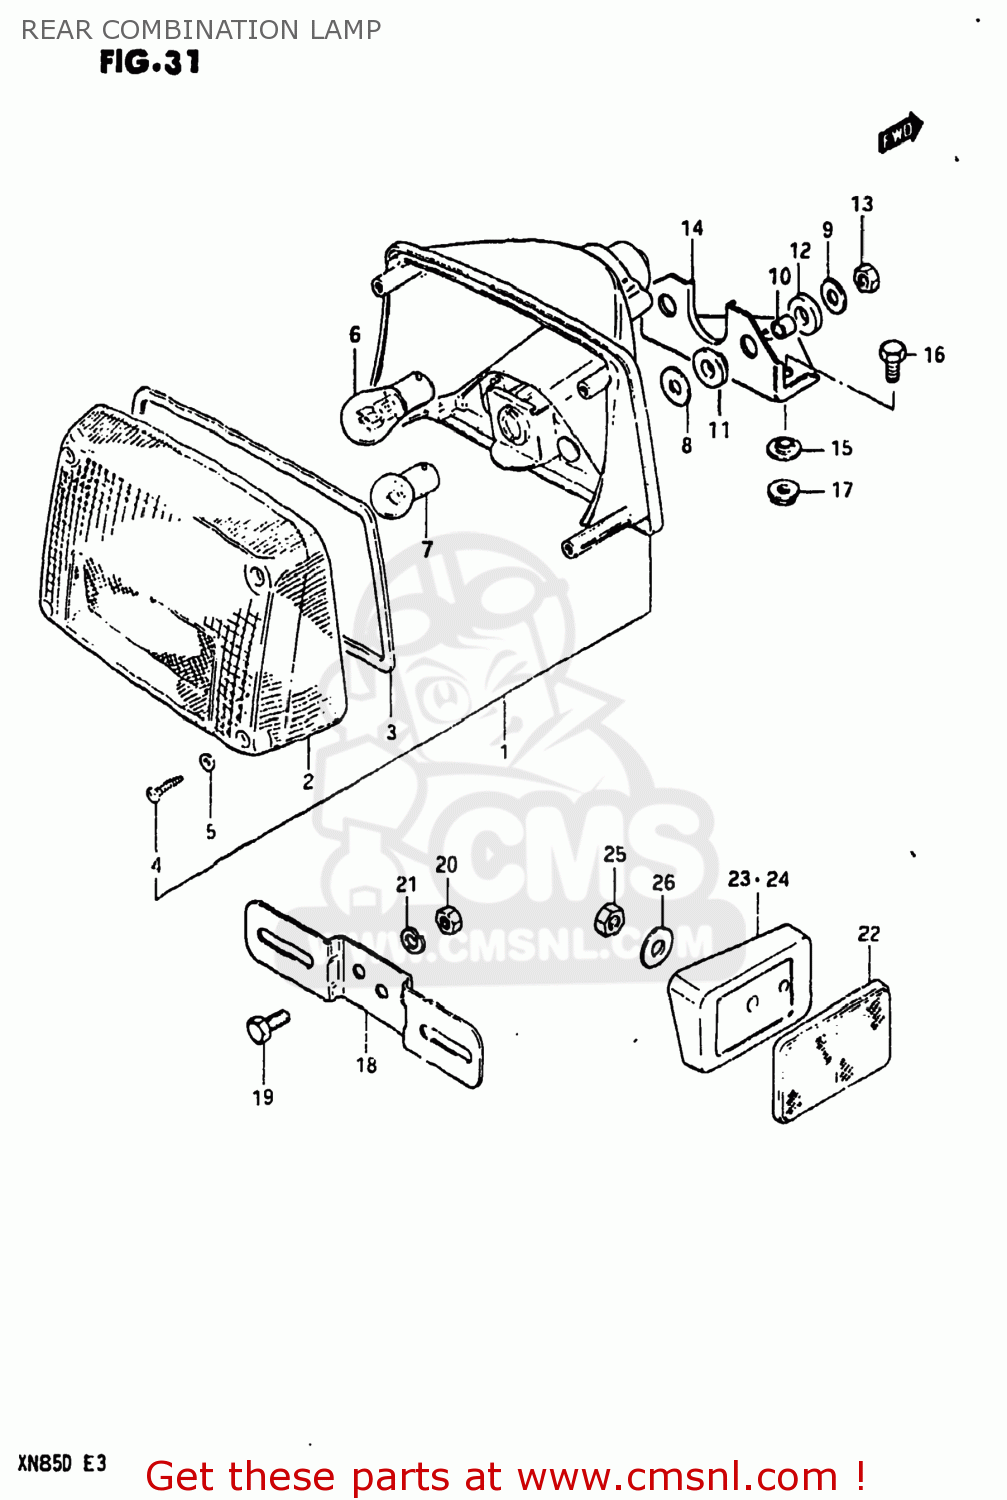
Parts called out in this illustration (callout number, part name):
1	LAMP ASSEMBLY,REAR COMBINATION
2	LENS
3	GASKET (NAS)
4	SCREW,REAR COMBINATION LAMP
5	GASKET (NAS)
6	BULB(12V23W)
7	BULB
8	WASHER
9	WASHER(6,5X22X1.6)
10	SPACER(6.1X9X7.5)
11	CUSHION
12	CUSHION
13	NUT 6MM
14	BRACKET,RR COMBINATION LAMP
15	WASHER
16	BOLT, UPPER
17	NUT 6MM
18	BRACKET,REAR LICENSE
19	BOLT,REAR
20	NUT
21	LOCK WASHER
22	REFLEX REFLECTOR,RR
23	SPACER
24	SPACER
25	NUT
26	WASHER(5.2X16X1)
